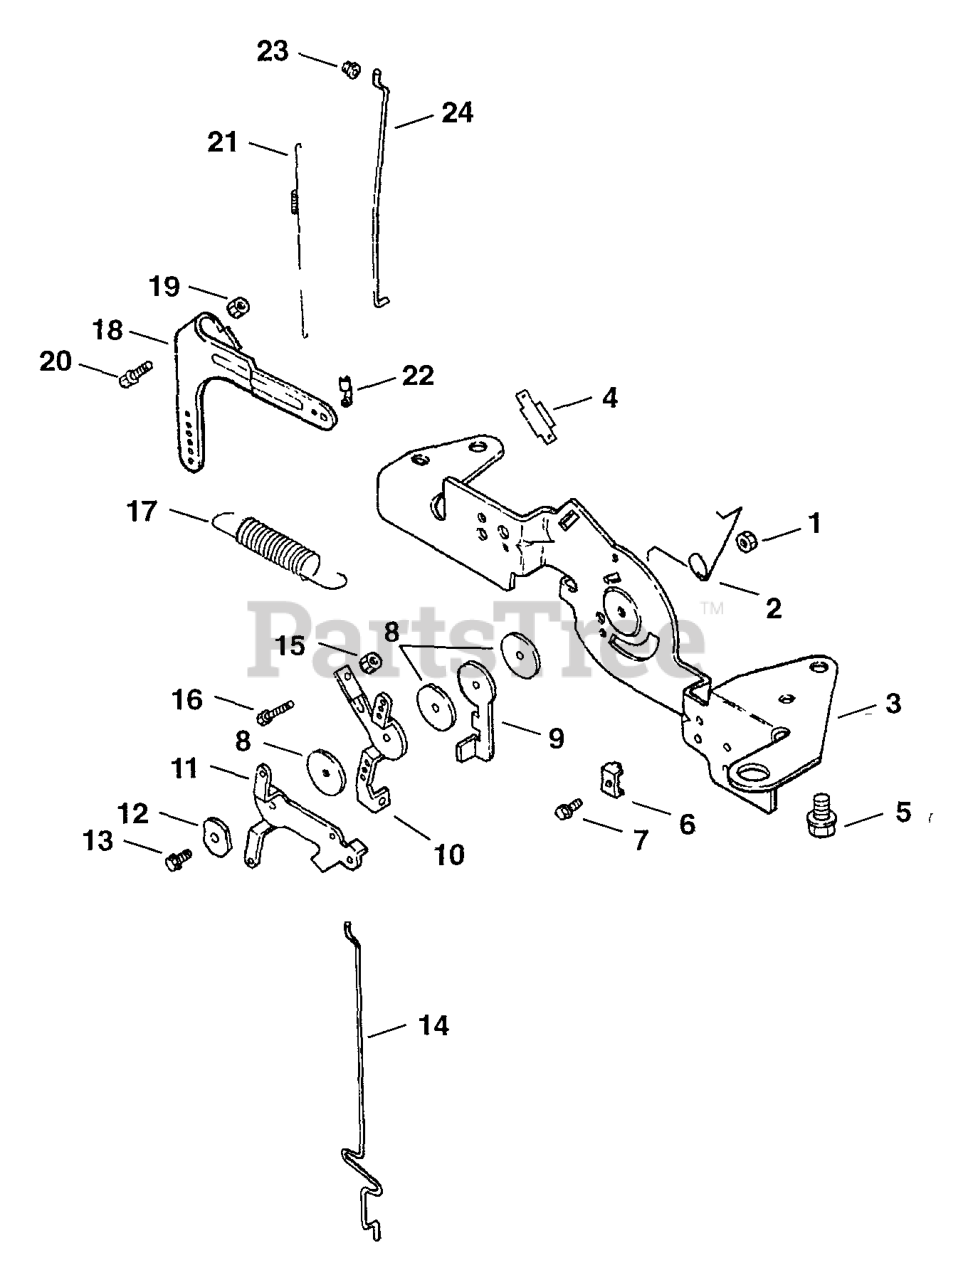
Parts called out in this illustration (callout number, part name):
5	Screw, Hex. Flange M6x1.0x16
6	Clamp, Cable
7	Screw, Hex. Flange M5x0.8x16
15	Nut, Hex. Flange M4x0.7
16	Screw, Hex. Cap M4x0.7x30
18	Lever, Governor
19	Nut, Hex. Flange M6x1.0
20	Screw, Hex. Cap M6x1.0x25
21	Spring, Linkage
22	Bushing, Linkage - Black
23	Bushing, Linkage - Natural
24	Linkage, Throttle
